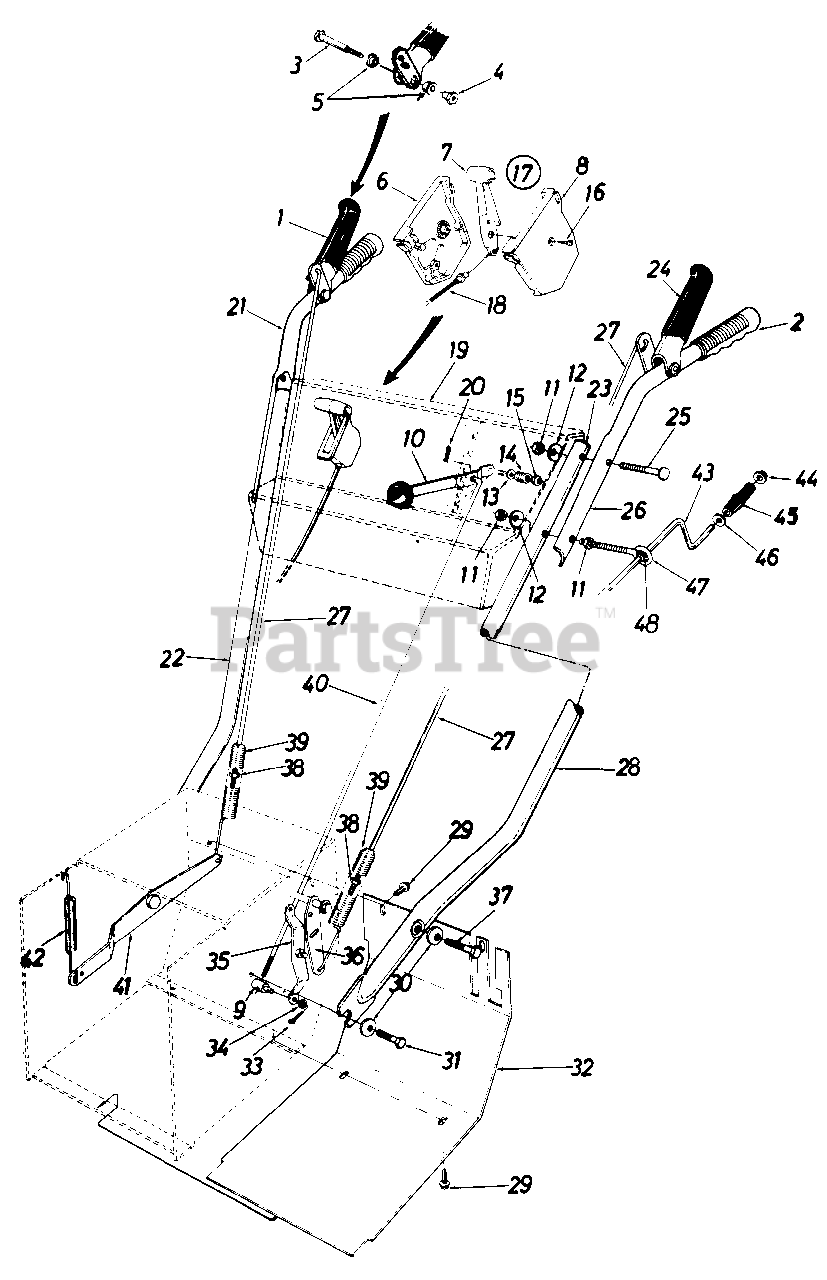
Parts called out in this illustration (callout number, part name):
1	Clutch Grip Ass'y. R.H.
2	Grip
3	Shoulder Bolt .374 Dia. x 1.53" Lg.
4	Shld. Nut 1/4-20 Thd.
5	Hex Flange Plastic Bearing .38" I.D.
9	Adjustment Ferrule
10	Shift Handle Ass'y.
11	Hex Nut 5/16-18 Thd.*
12	Bell-Wash. .34" I.D. x .88" O.D.
13	Bell-Wash. .40" I.D. x .88" O.D.
14	Compression Spring
15	Hex Ins. L-Nut 3/8-24 Thd.
17	Throttle Control Box Ass'y.
18	Throttle Control Wire
19	Handle Panel Ass'y.
20	Int. Cotter Pin 5/16" Dia.
21	Upper Handle R.H.
22	Lower Handle R.H.
23	Plastic Plug
24	Clutch Grip Ass'y. L.H.
25	Curved Carriage Bolt 5/16-18 x 2.0" Lg.
26	Upper Handle L.H.
28	Lower Handle L.H.
29	Hex Wash. Hd. Self-Tap Scr. 5/16-24 x .50" Lg.
30	Bell-Wash. .40" I.D. x .88" O.D.
31	Pilot Hex Scr. 3/8-16 x .88" Lg.
32	Frame Cover
33	Cotter Pin 3/32" Dia.*
34	Fl-Wash. .345 0 I.D. x .62 O.D. x .06
35	Shifting Linkage Brkt.
36	Drive Clutch Brkt. Ass'y.
37	Hex Bolt 3/8-16 x 2.0" Lg.*
38	Hex Ins. L-Nut 1/4-20 Thd.
39	Ext. Spring .75" O.D. x 5" Lg.
40	Shift Rod
41	Auger Clutch Brkt.
42	Ext. Spring .38" O.D. x 3.18" Lg.
43	Chute Crank Ass'y.
44	Push Nut 3/8" Rod
45	Knob 3/8" Rod
46	Fl-Wash. .40" I.D. x .62" O.D.
47	Eyebolt 5/16-18 x 5.0" Lg.
48	Grommet
